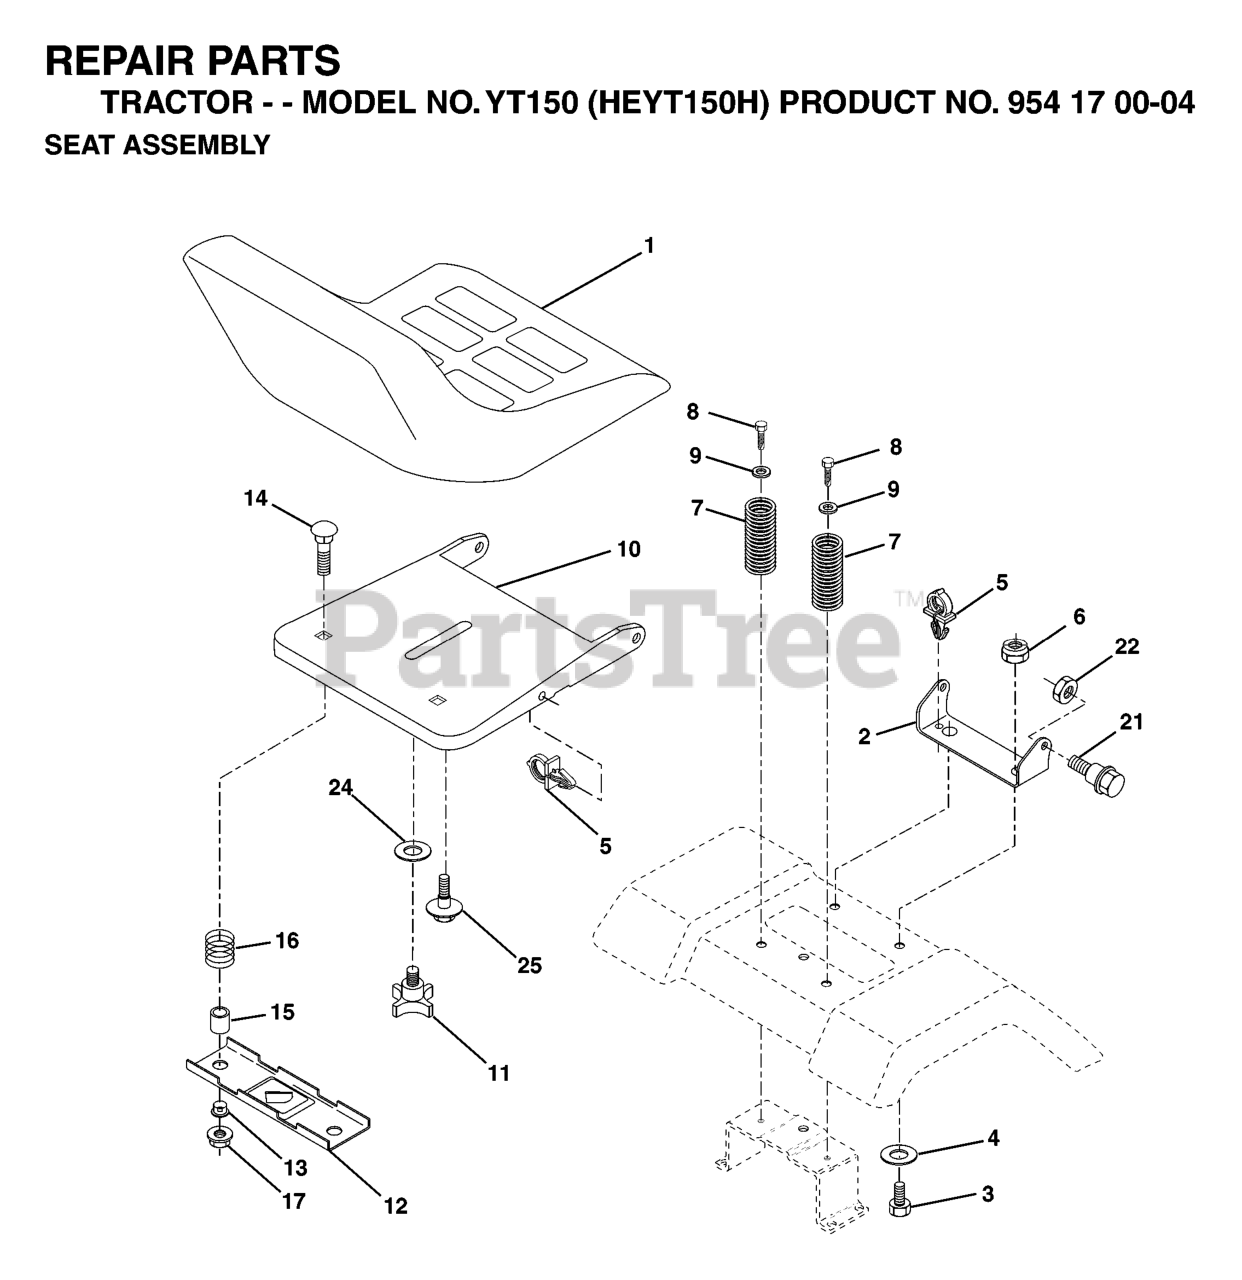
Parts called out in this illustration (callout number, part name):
1	SEAT, GRAY
2	SEAT PIVOT BRKT
3	BOLT
6	NUT
7	SPRING COMPRESSION
8	SCREW GTV
9	WASHER
10	PAN, SEAT
11	KNOB 1/2" YT
12	BRKT SWITCH
14	BOLT.ROUND.HEAD.SQUARE.NECK
15	SPACER SPLIT 28X.96
17	NUT T
21	BOLT SHOULDER 5/16-18
22	NUT.71038.31-18.HEX.NYLOCK
25	BOLT,SHOULD
